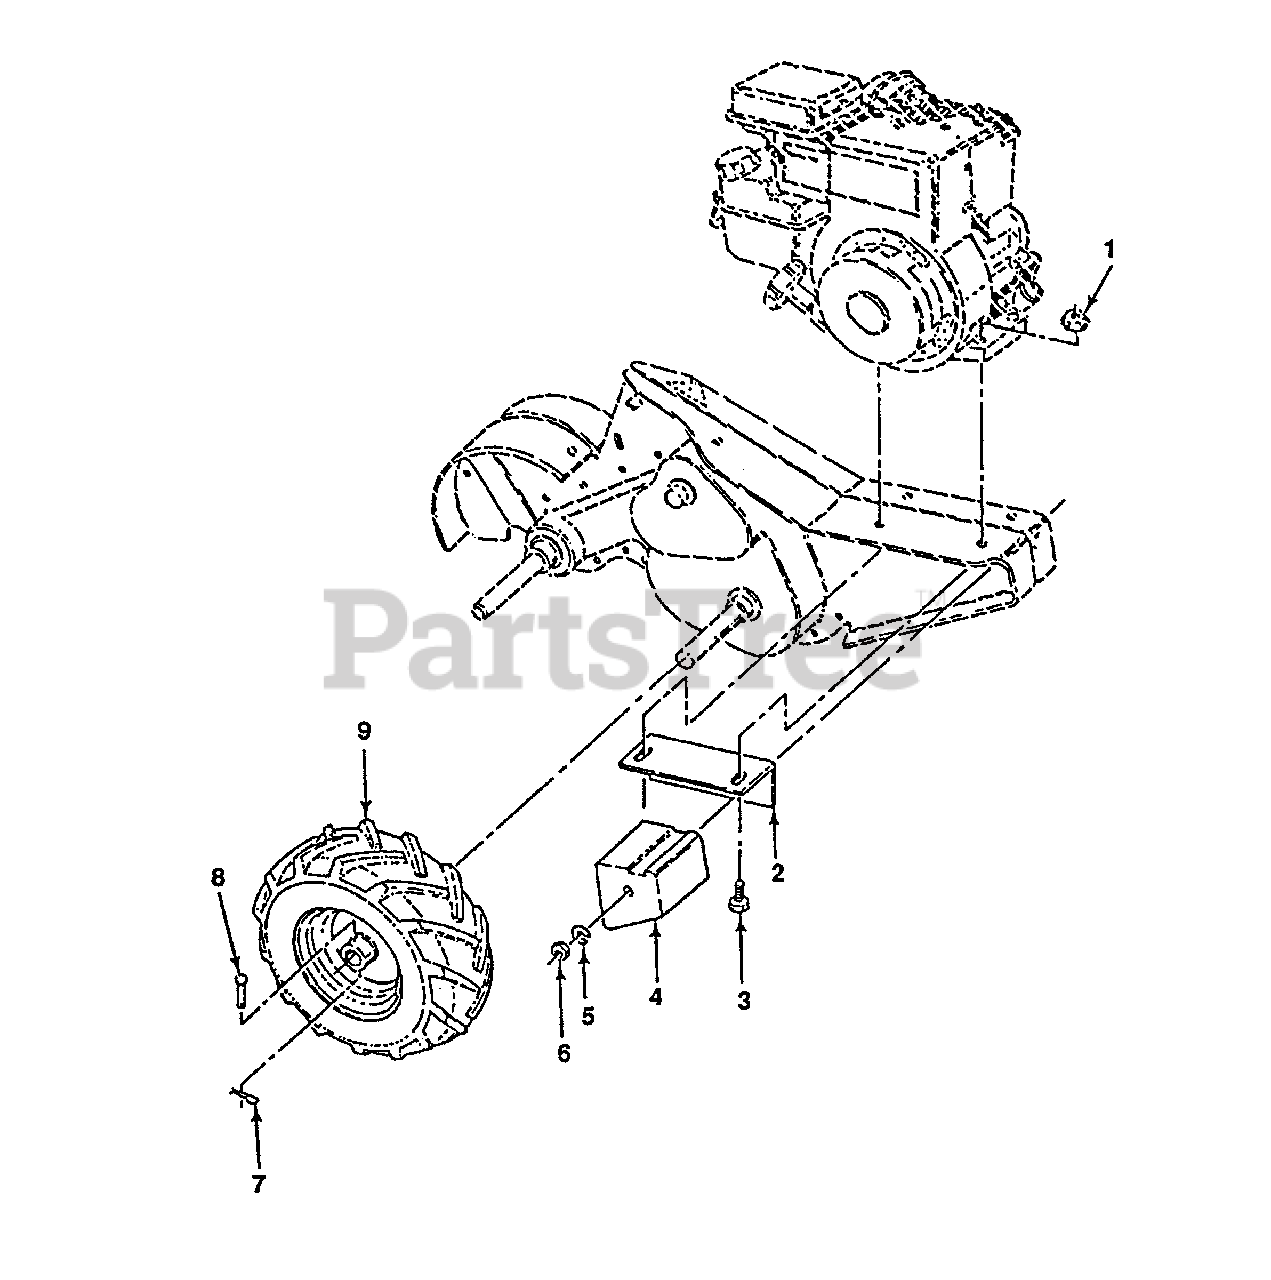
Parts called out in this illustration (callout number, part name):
1	Nut, Keps 5/16-18
2	Bracket, Reinforcment
3	Bolt, Hex 5/16-18 x 1-1/2
4	Counter Weight, R.H.
5	Washer, Lock 3/8
6	Nut, Hex 3/8-16
7	Clip, Hairpin
8	Rivet, Drilled
9	Tire Valve
